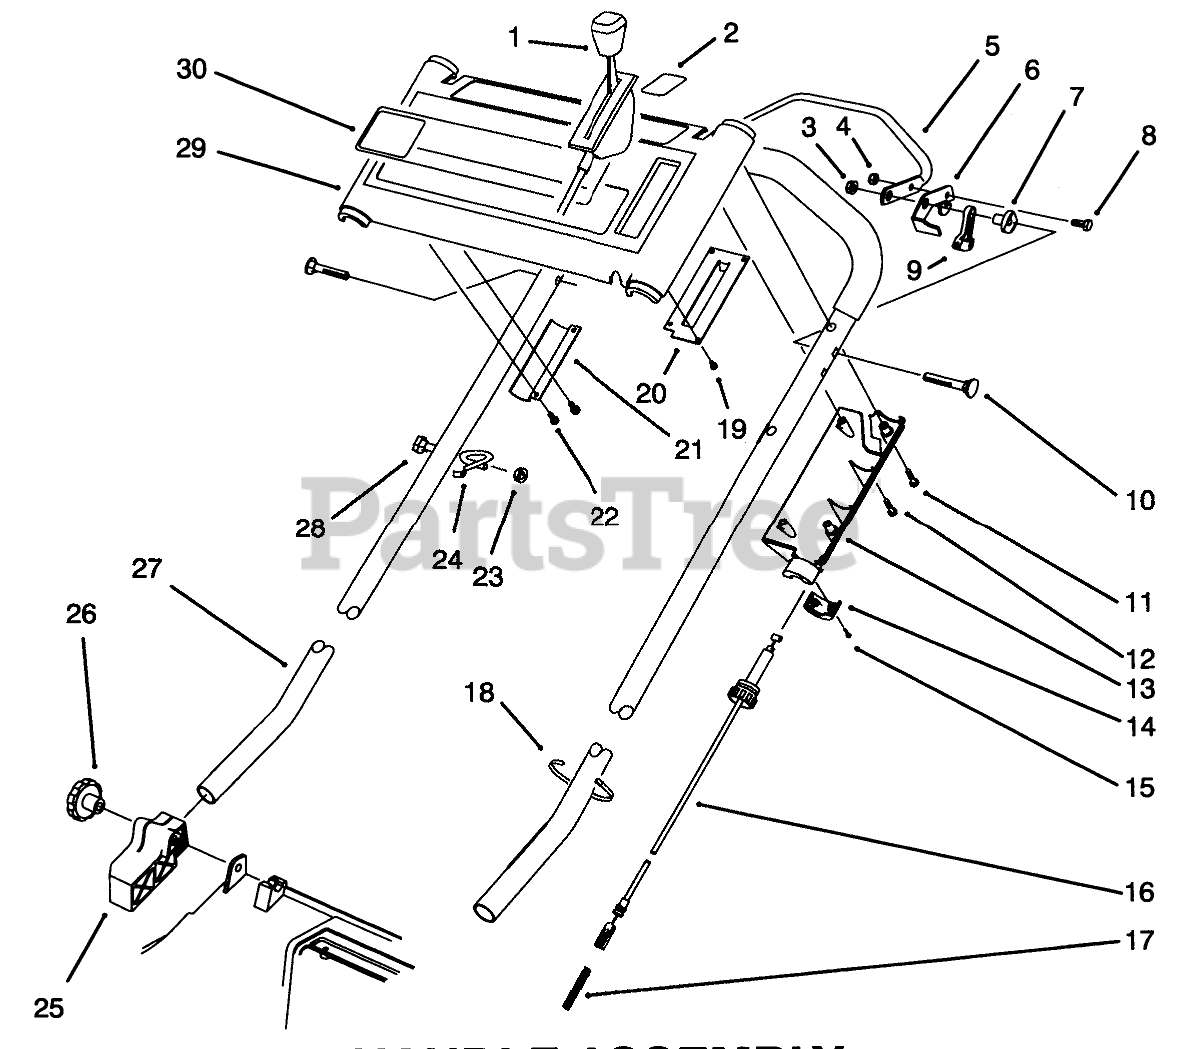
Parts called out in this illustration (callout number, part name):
1	THROTTLE CONTROL
2	DECAL - PANEL
3	NUT-LOCK, NI
4	NUT-LOCK, NI
5	CONTROL BAR
6	LEVER-CONTROL
7	SPACER-SUPPORT
8	SCREW-HH
9	LEVER-TRACTION
10	SCREW-HANDLE
11	SCREW-PPH, PLASTITE
12	Screw
13	Cover-Throttle Lower
14	LOWER THROTTLE CAP
15	#4-14X.62 PLASTITE SCW
16	TRACTION CABLE
17	SPRING-COMPRESSION
18	TIE-CABLE
19	#6-19X.25 PLASK FORM SC
20	THROTTLE PLATE
21	Bracket-Panel
22	SCREW-PPH, PLASTITE
23	NUT-LOCK, NI
24	GUIDE-ROPE
25	MOUNT-HANDLE, RH
27	HANDLE (DIPPED)
28	SCREW-HH
29	Panel-Control (Incl. Ref. #2, & 30)
30	DECAL - PANEL
